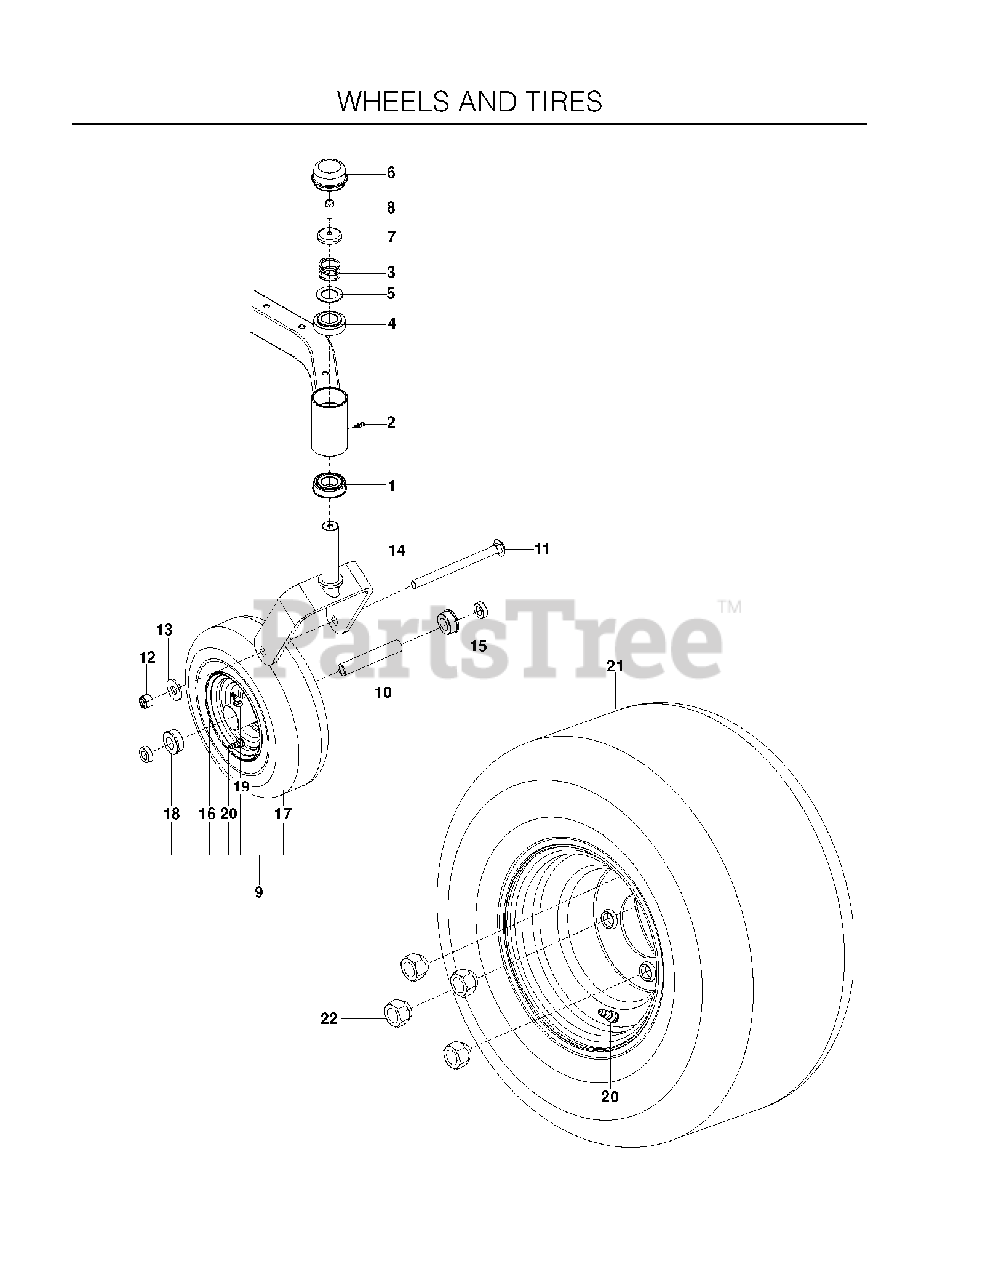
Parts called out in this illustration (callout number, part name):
1	BEARING FLANGED
2	ZERK, 3/16, DRIVE IN
3	SPRING, CASTER
4	BUSHING, CASTER
5	WASHER, 1.025 ID X 1.64
6	GREASE CAP
7	CASTER.PLUG
8	5/16-18X1 HHB G5W/NY
9	TIRE, CASTER, COMPLETE
11	RHSNB 1/2-13 X 6.50 GR2 ZD
12	NUT 1/2-13 HEX CNTRLK GR 5 ZD
13	WASH USS FLAT 1/2
14	CASTER DK BLUE
15	SPACER, 5/16"
17	TIRE, 4. 10-5.4 PLY
18	BUSHING, WHEEL, 3/4"
19	ZERK
20	VALVE STEM TR-412
21	TIRE ASM 18 X 8.5-8
22	LUG NUT 1/2F
